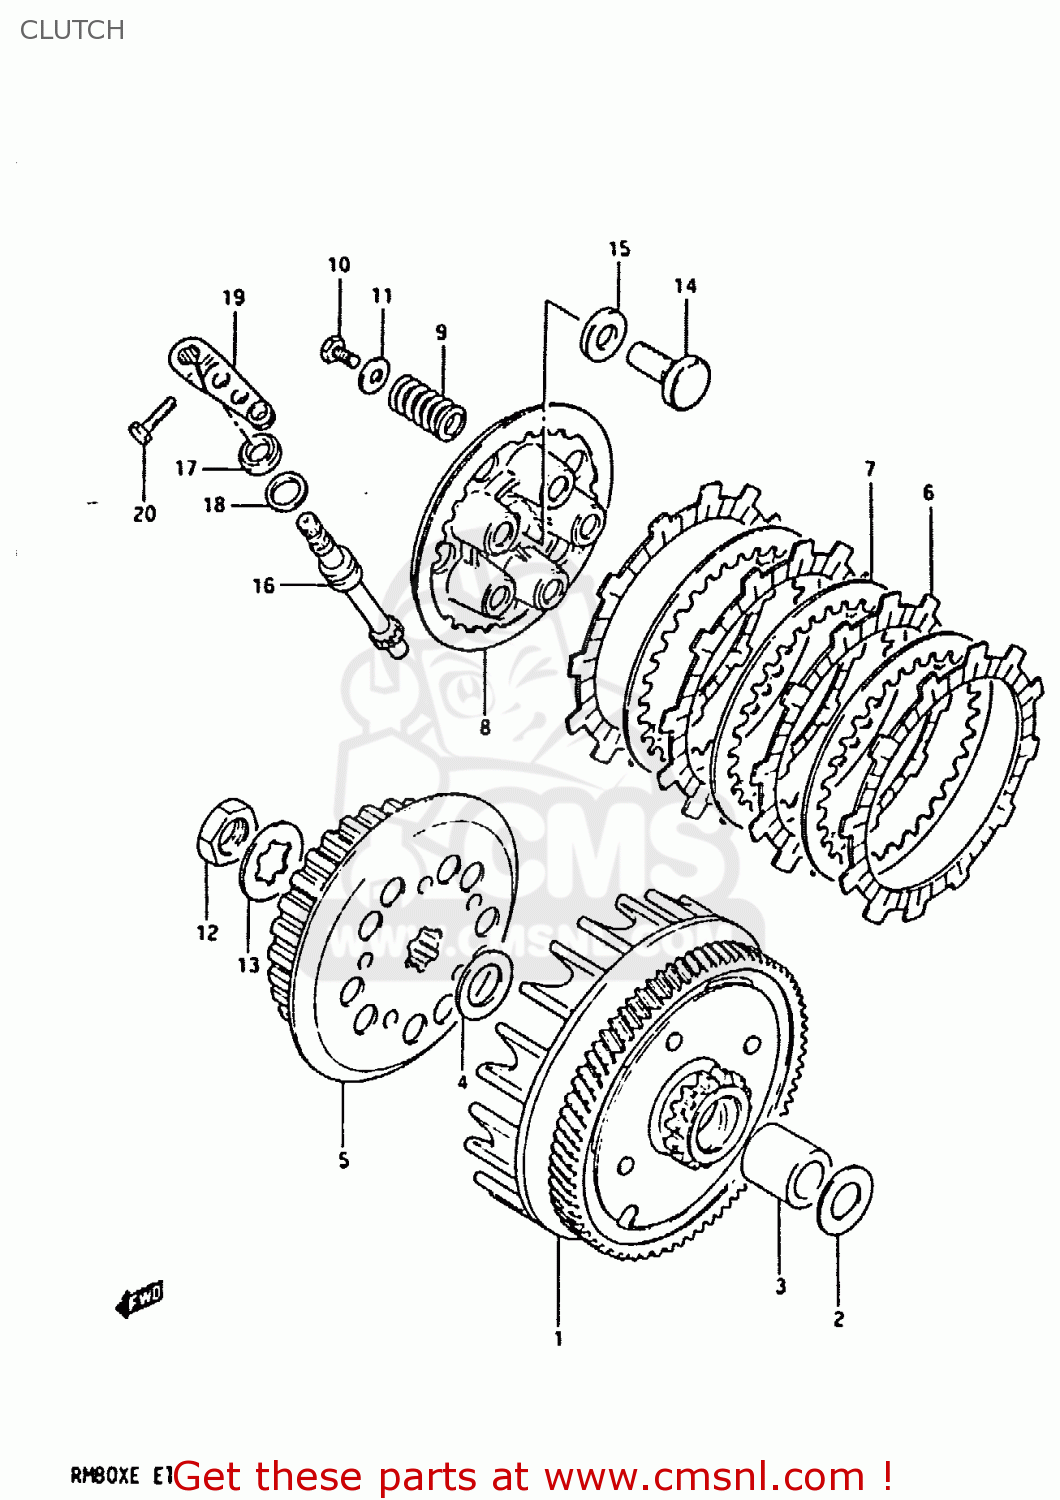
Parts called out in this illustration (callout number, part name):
1	GEAR ASSEMBLY,PRIMARY DRIVE
2	WASHER,THRUST
3	SPACER(17X22X28.5)
4	WASHER
5	HUB,CLUTCH SLEEVE
6	PLATE,CLUTCH DRIVE
7	PLATE,CLUTCH DRIVEN (NAS)
8	DISC,CLUTCH PRESSURE
9	SPRING
10	BOLT(5X16)
11	WASHER (5.5X16X1.2)
12	NUT
13	WASHER,LOCK
14	RACK,CLUTCH RELEASE
15	BEARING(10X22X2.8)
16	PINION,CLUTCH RELEASE
17	SEAL,OIL(10X17X5)
18	WASHER (12X17X1)
19	ARM,CLUTCH RELEASE
20	BOLT, UPPER
